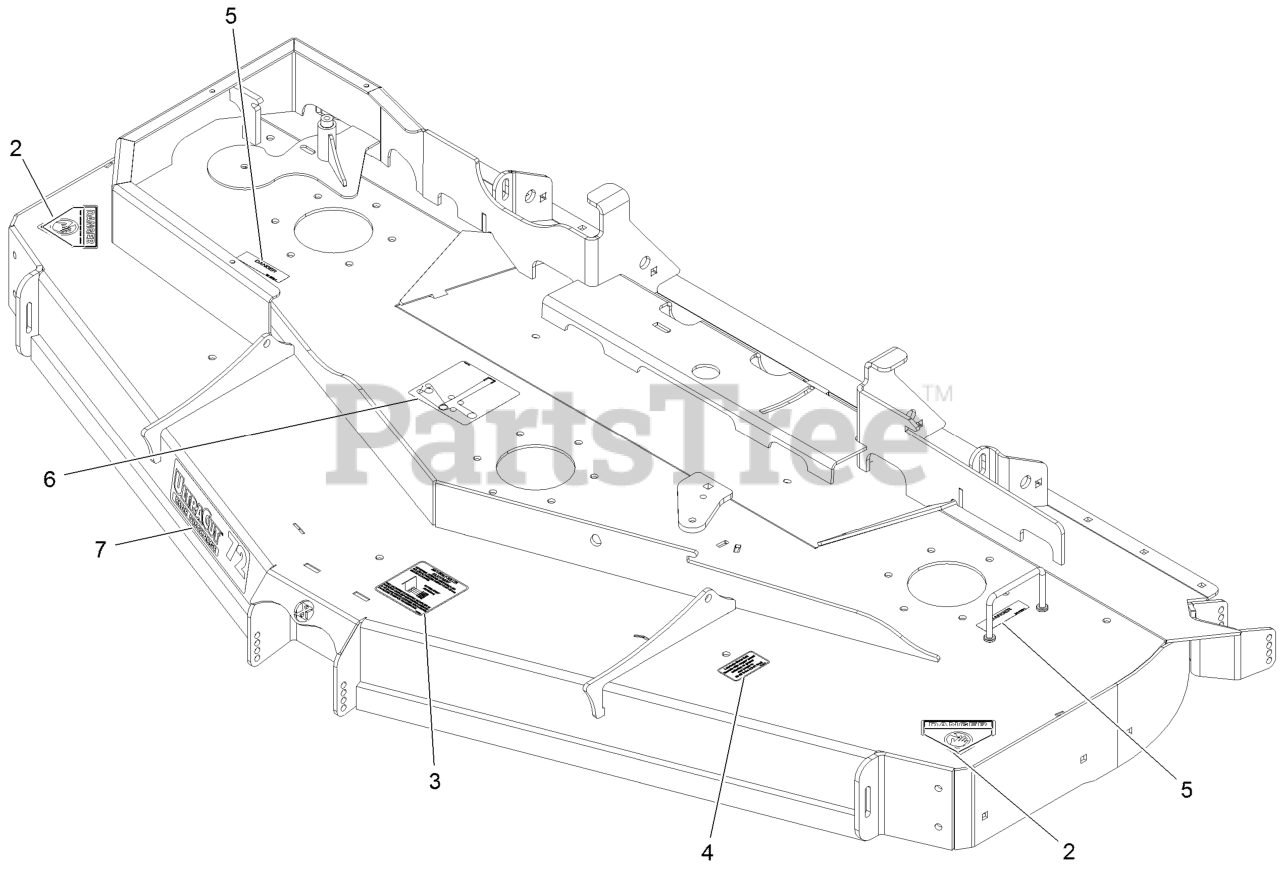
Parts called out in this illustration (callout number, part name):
2	DECAL-DANGER
3	DECAL,ANTISCALP
4	DECAL,BOLT TORQUE
5	DECAL-COVER, MISSING
6	DECAL,BELT ROUTING RD DEC
7	DECAL,REAR DISCHARGE 72
